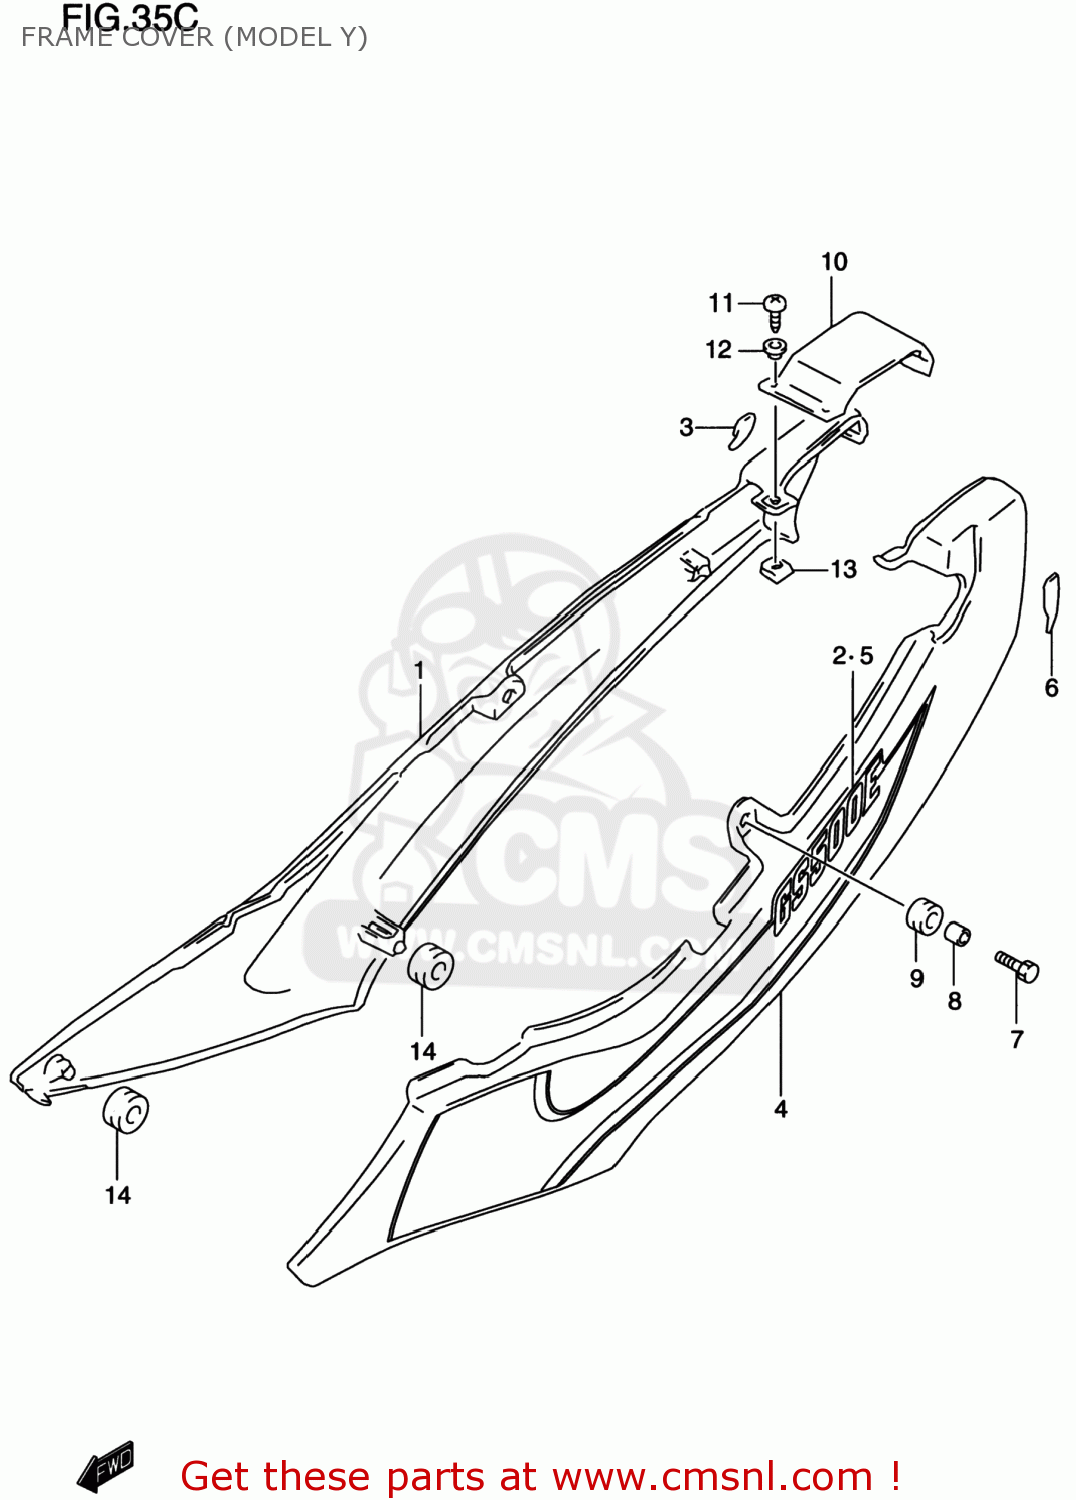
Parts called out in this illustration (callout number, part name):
1	COVER,FRAME,R(BLACK)
2	TAPE,FRAME COVER,R
3	PROTECTOR,FRAME COVER,R
4	COVER,FRAME,L(BLACK)
5	TAPE,FRAME COVER,LEFT
6	PROTECTOR,FRAME COVER,L
7	BOLT(6X20)
8	SPACER(6.5X9X9)
9	CUSHION
10	COVER,FRAME CTR
11	SCREW
12	WASHER(5.2X14X1.5)
13	NUT
14	CUSHION
